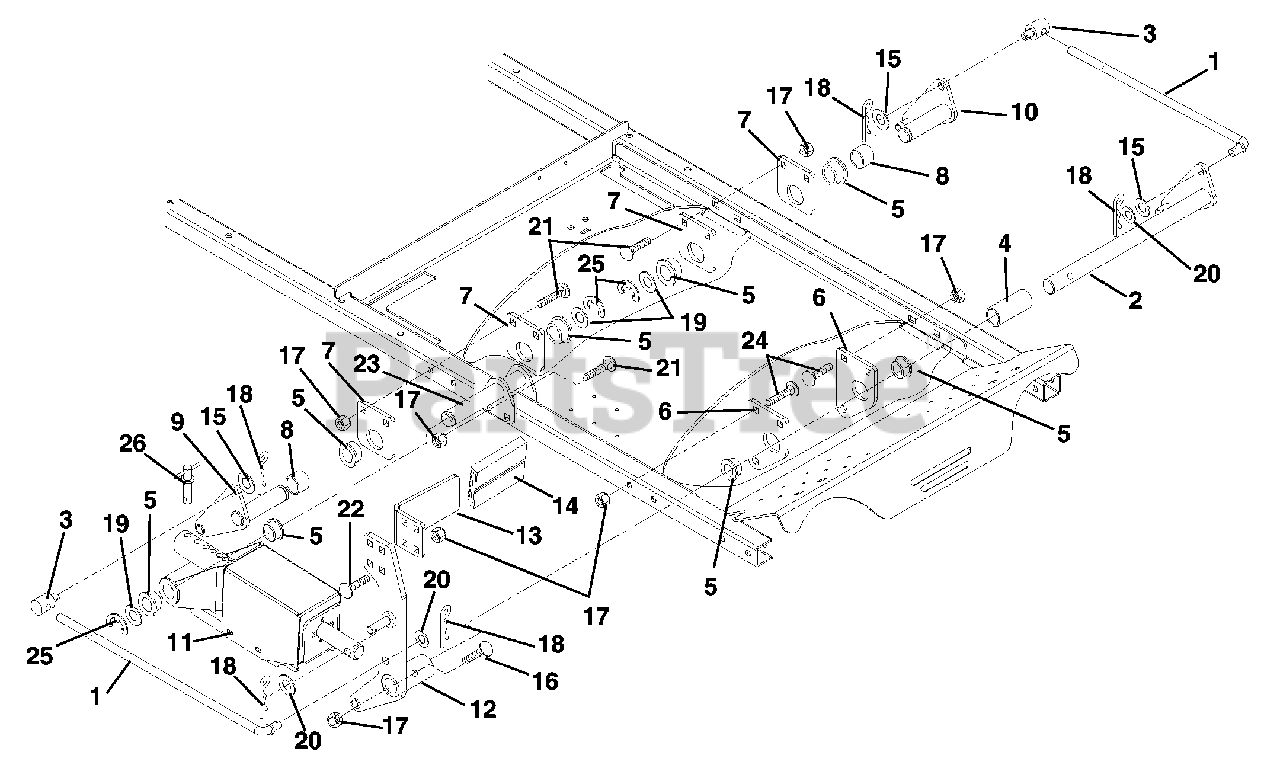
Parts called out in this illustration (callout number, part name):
1	LINKAGE, LIFT
2	WELDMENT, LIFT, FRONT
3	TRUNNION-.50
4	BUSHING, FRONT
5	BSHG-FLG1.020X1.385X.75X1.75NY
6	BRACKET, MOUNT, FRONT
7	BRACKET, MOUNT, REAR
8	BSHG-SPCR 1.032X1.250X.88 PM
9	WELDMENT, LIFT, REAR - RH
10	WELDMENT, LIFT, REAR - LH
11	ZOOM LIFT ASSEMBLY
12	WELDMENT, LIFT PEDAL MOUNT
13	PEDAL, FOOT LIFT
14	PAD,PEDAL
15	WSHR-FL-STL.511X1.441X.125 BZ
16	@BLT-HEX .38-16X2.00 GR5 YWZC
17	NUT-LK-TOP-FLG .38-16 BLKZC
18	PIN, HAIR, EXT - #16 YWZC
19	WSHR-FL-STL- 1.062X2.0X.134 YZ
20	@WSHR-FL-STL.531X1.06X.095YWZC
21	BLT-RDHDSQNK .38-16X2.50 G5BZ
22	BLT-RDHDSQNK .38-16X1.00 G5BZ
23	WELDMENT, PIVOT MOUNT
24	BLT-RDHDSQNK .38-16X2.25 G5BZ
25	RG-RTNG .822X1.500X.050 TYP E
26	PIN, SPRING BALL .375OD X 1.50
